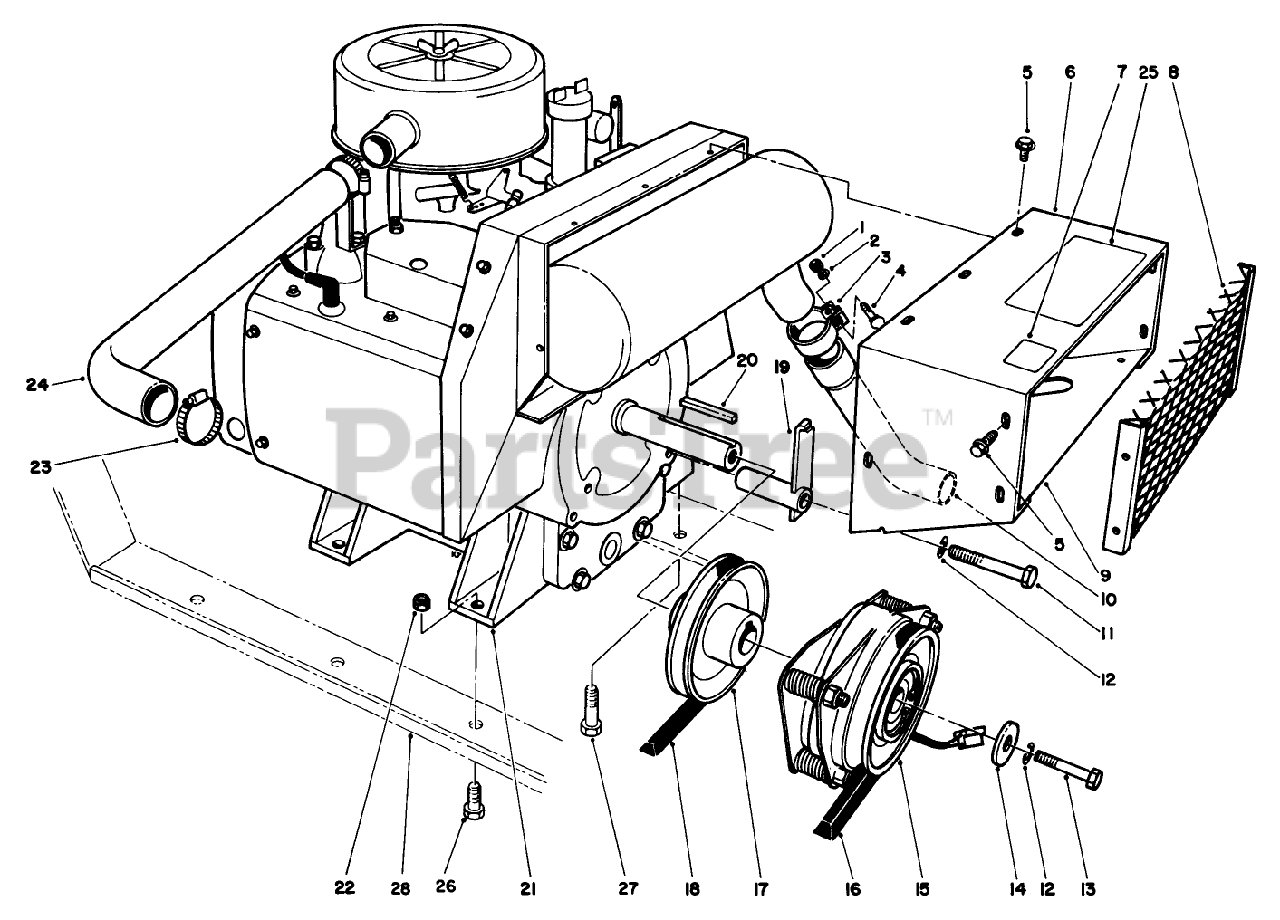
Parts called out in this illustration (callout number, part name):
1	NUT-HEX
2	WASHER-LOCK
3	Clamp Assembly (Incl. Ref. #1, 2 & 4)
4	SCREW-CARR
5	SCREW-HHFTF
6	ENGINE DUCT WA B
7	DECAL-SURFACE, HOT
8	Screen
9	BOTTOM DUCT B
10	EXHAUST PIPE
11	SCREW-HH
12	WASHER-LOCK
13	SCREW-HH
14	WASHER-CLUTCH
15	BRAKE CLUTCH ASM
16	V-BELT, JACKSHAFT
17	ENGINE PULLEY
18	V-BELT, TRACTION
19	Anchor Bracket
21	Engine-Kohler Model No. M18QS-24657
22	NUT-LOCK, NI
23	CLAMP-HOSE
24	AIR CLEANER HOSE
25	DECAL - SERVICE INSTR.
26	SCREW-HH
27	SCREW-HWHTF
28	Mount-Engine (Ref.)
